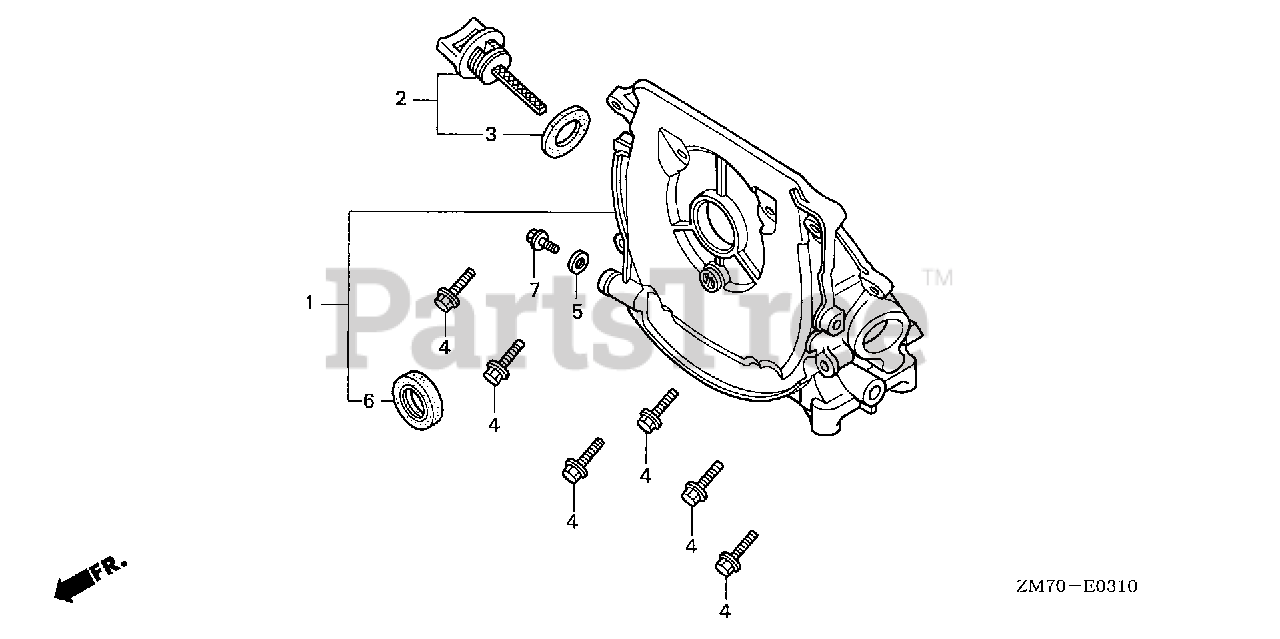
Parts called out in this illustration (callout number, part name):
1	CASE ASSY., OIL
2	CAP ASSY., OIL FILLER
3	GASKET, OIL FILLER CAP
4	BOLT, FLANGE (5X23)
5	GASKET (8MM)
6	OIL SEAL (17X27X5) (KOYO)
7	BOLT, FLANGE (8X12)
